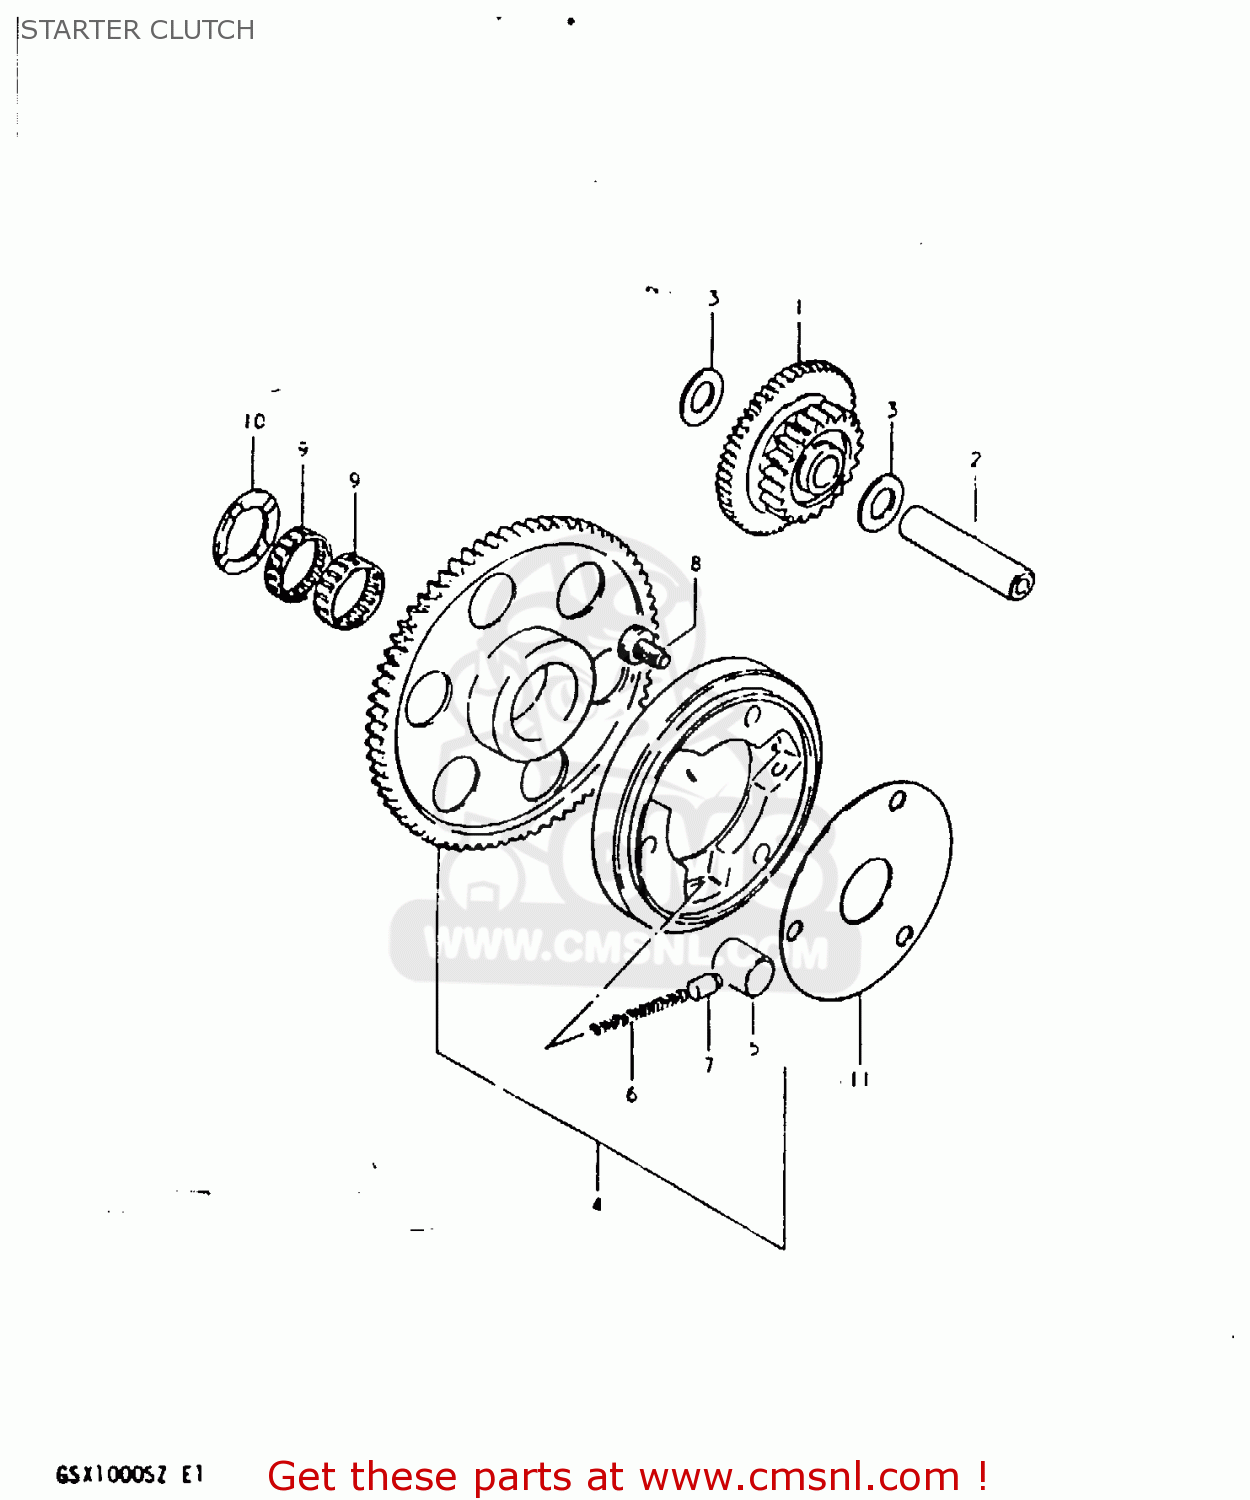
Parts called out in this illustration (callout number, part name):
1	GEAR,STARTER IDLE
2	PIN(7.4X13X56)
3	WASHER(13.3X25X0.85)
4	CLUTCH SET,STARTER
5	ROLLER(15X13)
6	SPRING
7	PIECE,PUSH
8	BOLT
9	BEARING
10	WASHER(25X38X2.5)
11	SHIM,STARTER CLUTCH HUB
